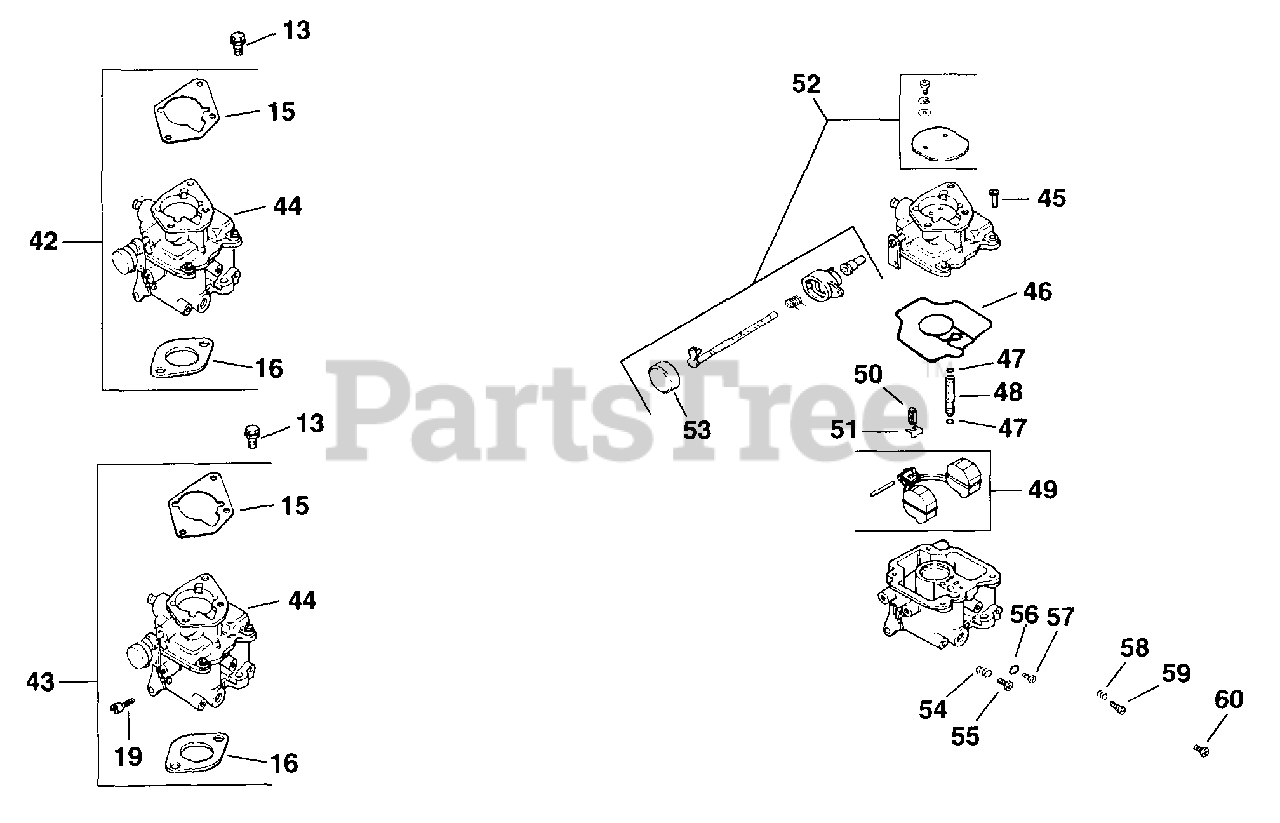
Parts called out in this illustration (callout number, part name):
13	SCREW - USE M-651030
15	GASKET, AIR CLEANER BASE
16	GASKET, CARBURETOR
42	CARBURETOR - USE 24 853 31
44	Carburetor assembly
45	SCREW, CARBURETOR BODY
46	GASKET, CARBURETOR BODY
47	O-RING, SLOW JET
48	JET, SLOW
49	KIT, REPAIR FLOAT
50	VALVE, INLET NEEDLE
51	CLIP, INLET NEEDLE VALVE
52	KIT, REPAIR CHOKE
53	CAP, CHOKE LEVER
54	SPRING, IDLE SPEED ADJ SCREW
55	SCREW, IDLE
56	O-RING, MAIN JET SCREW
57	JET, MAIN
58	SPRING, IDLE NEEDLE
59	NEEDLE, IDLE
60	SCREW, FLG M8X1.00X10
